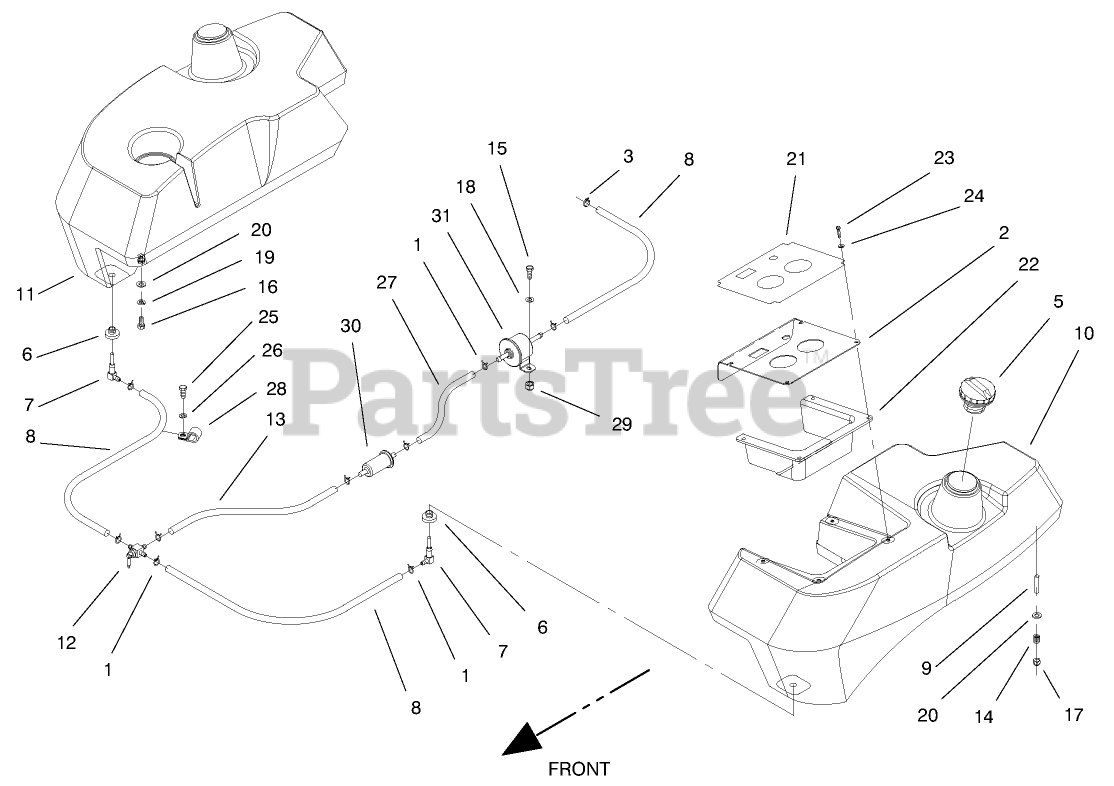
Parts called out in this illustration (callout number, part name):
1	Clamp
2	PANEL-CONTROL
3	Clamp
5	CAP-FUEL
6	Bushing
7	Elbow
8	Fuel Line
9	Stud
10	TANK-FUEL, LH
11	TANK-FUEL, RH
12	Valve-Fuel Line
13	Fuel Line
14	Spring-Fuel Tank
15	SCREW-HH
16	SCREW-HH
17	NUT-LOCK, NI
18	WASHER-FLAT
19	WASHER-LOCK
20	WASHER-PLAIN
21	DECAL-CONTROL PANEL
22	SHIELD-PANEL, CONTROL
23	Screw
24	Washer
25	SCREW-HH
26	WASHER-LOCK
27	Fuel Line
28	Clip
29	NUT-HF
30	Filter-Fuel
31	PUMP-FUEL
